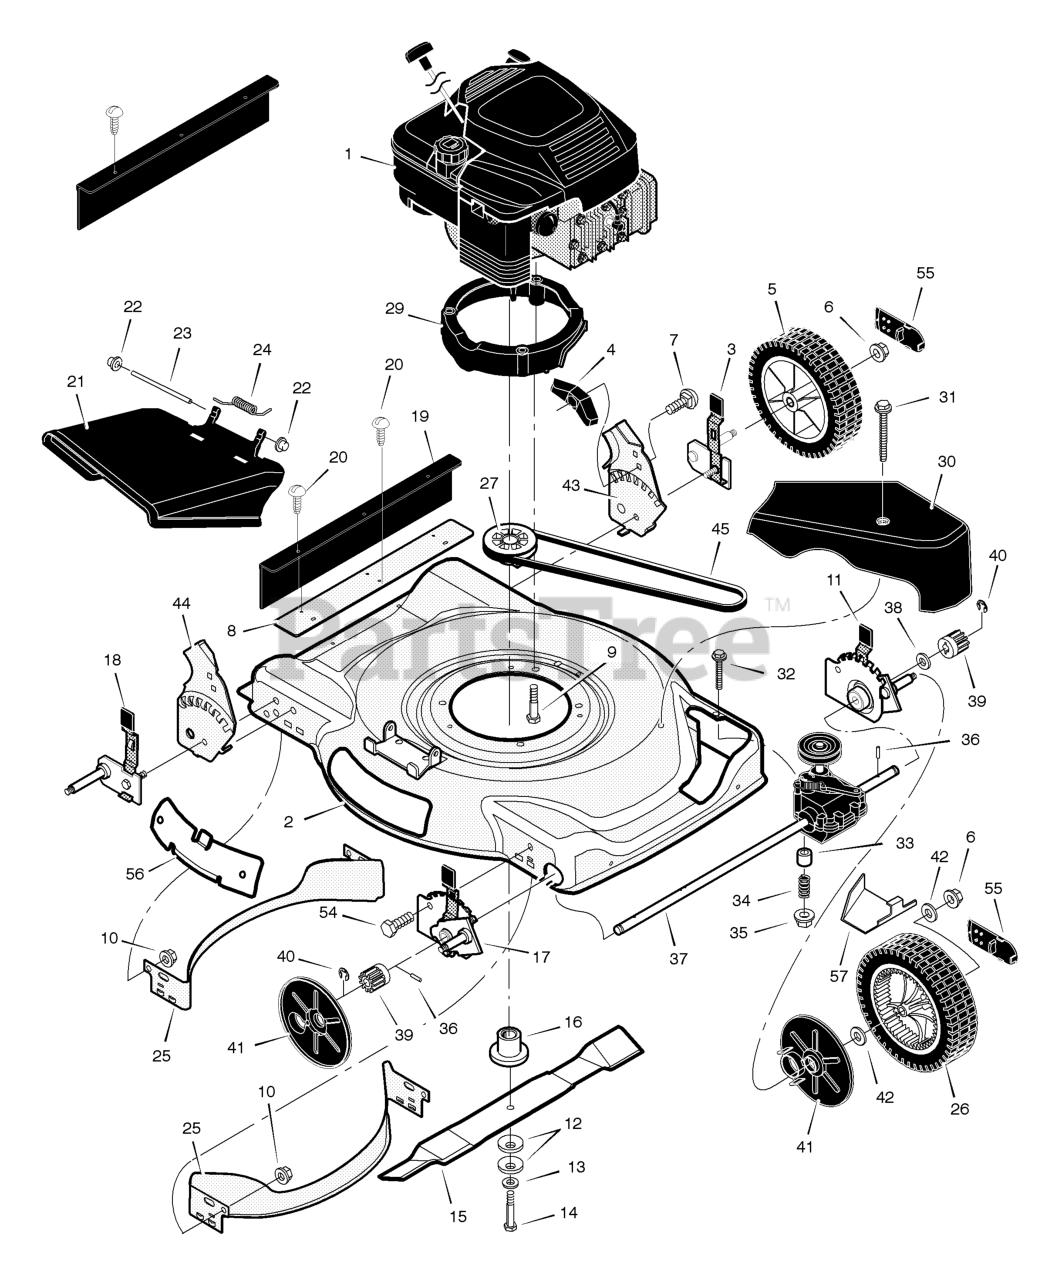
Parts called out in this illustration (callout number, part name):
1	Engine *
2	Housing
3	Height Adjuster, Left Rear
5	Wheel and Tire, Rear
6	Locknut, Flange
7	Bolt, Carriage
8	Extension, Rear
9	Bolt, Engine
10	Nut
11	Height Adjuster, Left Front
12	Washer, Belleville
14	Bolt, Hex
16	Adapter, Blade
17	Height, Adjuster, Right Frt.
18	Height, Adjuster, Right Rr.
19	Guard, Rear
21	Deflector, Chute
22	Push-On Cap
23	Pin, Pivot
25	Baffle
26	Wheel and Tire, Drive
29	Base, Engine
30	Cover, Belt (Black)
30	Cover, Belt (Gray)
35	Nut
36	Pin, Drive
37	Transmission *
39	Gear, Pinion
41	Cover, Dust
42	Washer
43	Bracket, Left Handle
44	Bracket, Right Handle
45	Belt, Briggs & Stratton
54	Bolt
55	Hub Cap
56	Plate, Mulch
57	Cover, Transmission
